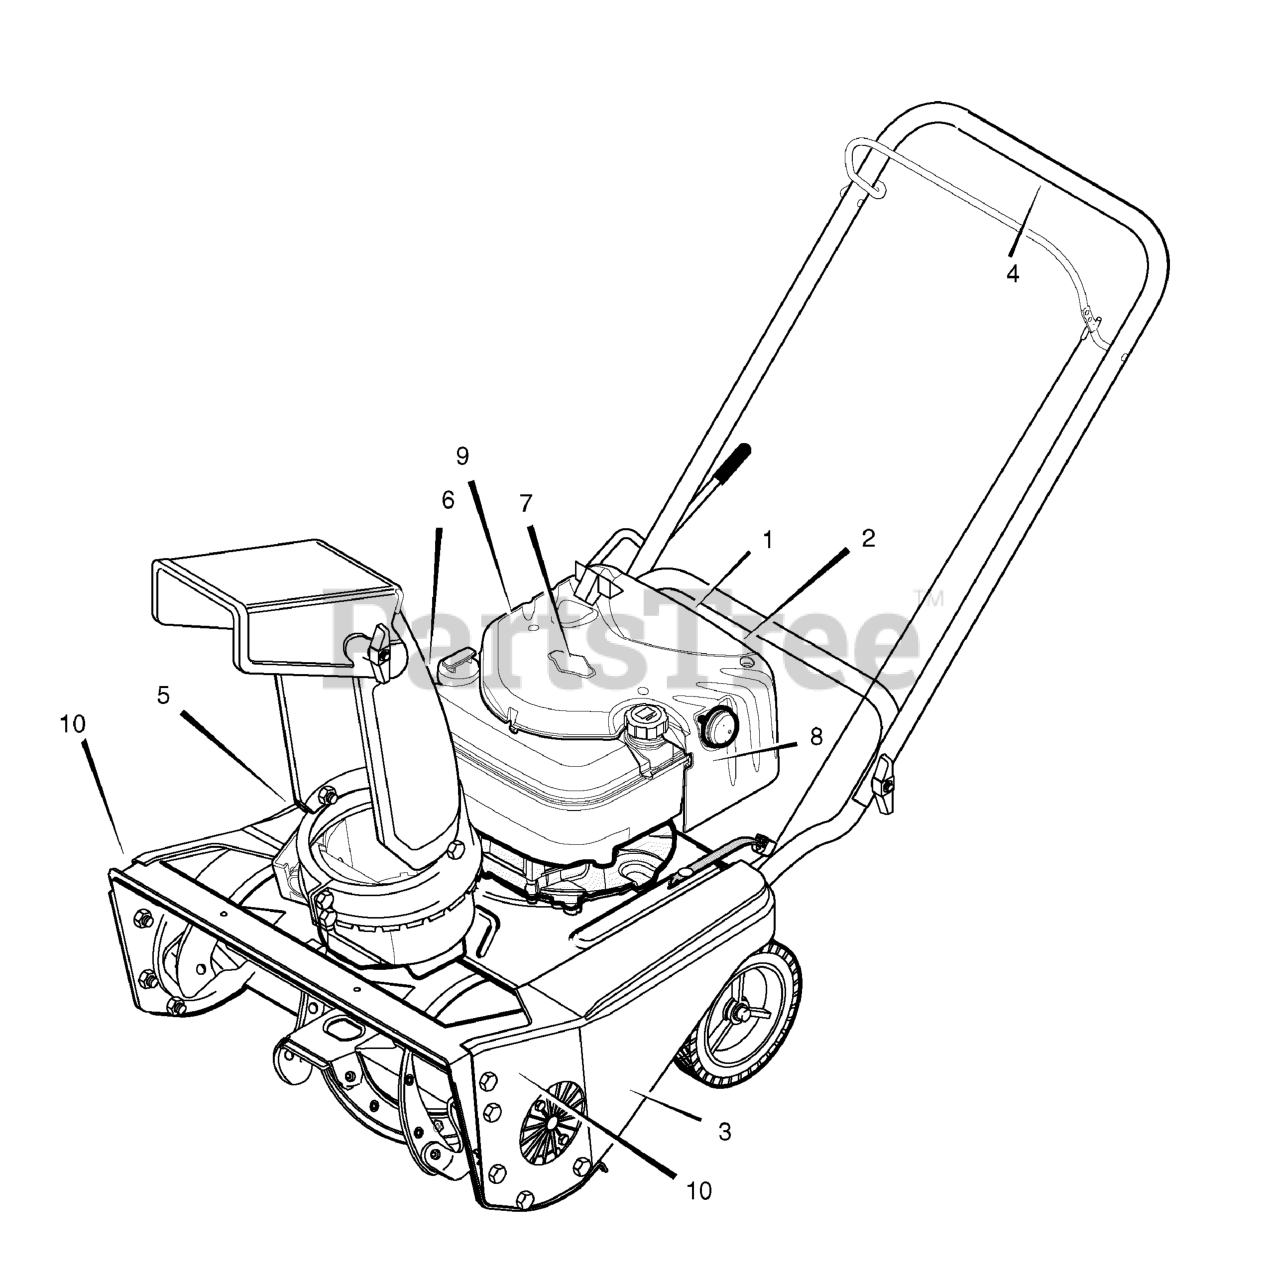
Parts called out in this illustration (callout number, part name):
1	Decal, 4hp / 21"
2	Decal, Choke
3	Decal, Belt Instruction (inside cover)
4	Decal, Auger Control Lever
5	Decal, Danger Auger (Foot)
6	Decal, Danger Chute (Hand)
7	Decal, Briggs & Stratton
8	Decal, Primer Bulb
9	Decal, Hot Surface
10	Decal, STIGA
